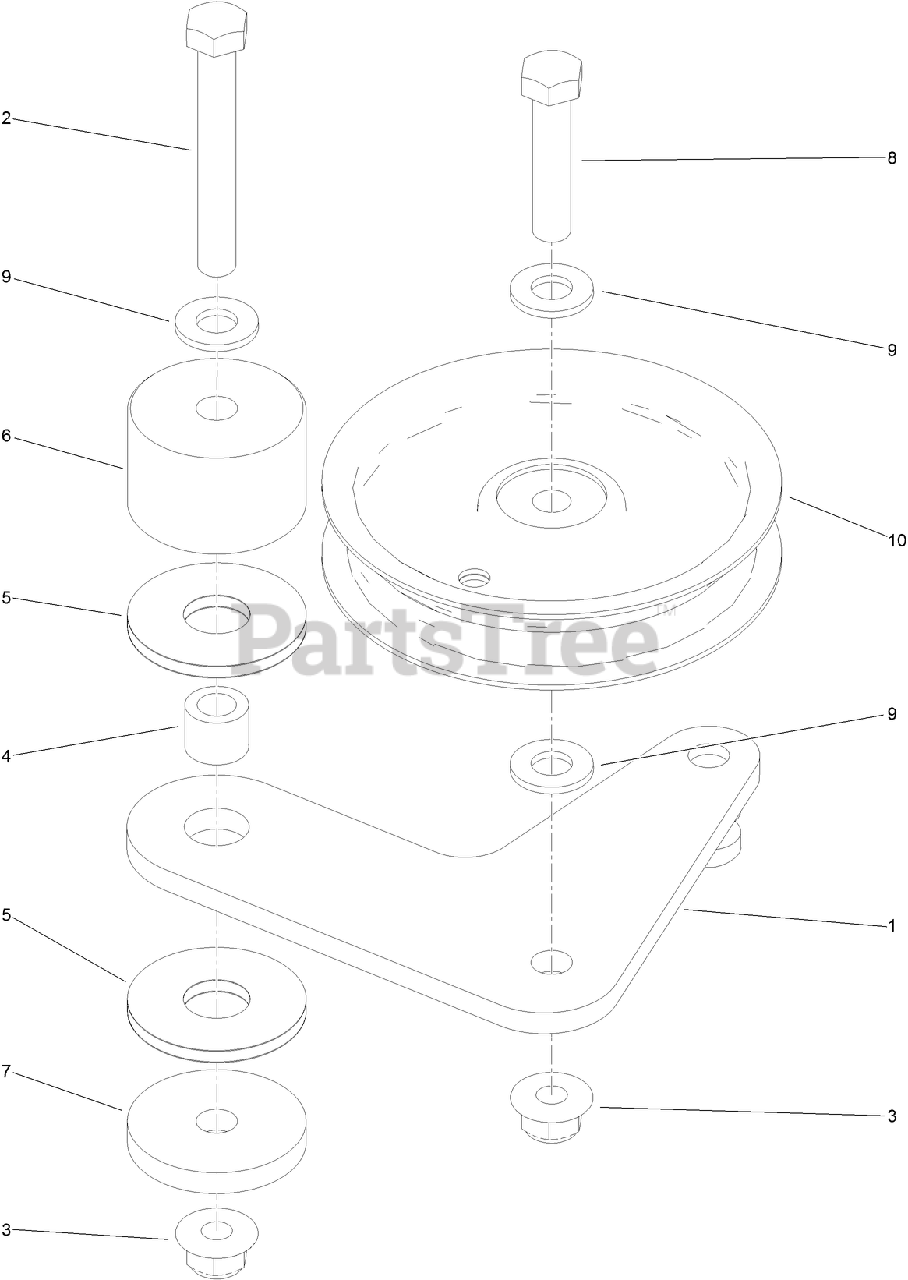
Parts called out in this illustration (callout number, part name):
1	PLATE-IDLER
2	SCREW-HH
3	NUT-HF, NI
4	BUSHING-LEVER, LIFT
5	WASHER-FRICTION, COMPOSITE
6	HUB, IDLER
7	WASHER-PLAIN
8	SCREW-HH
9	WASHER-FLAT
10	PULLEY-IDLER
